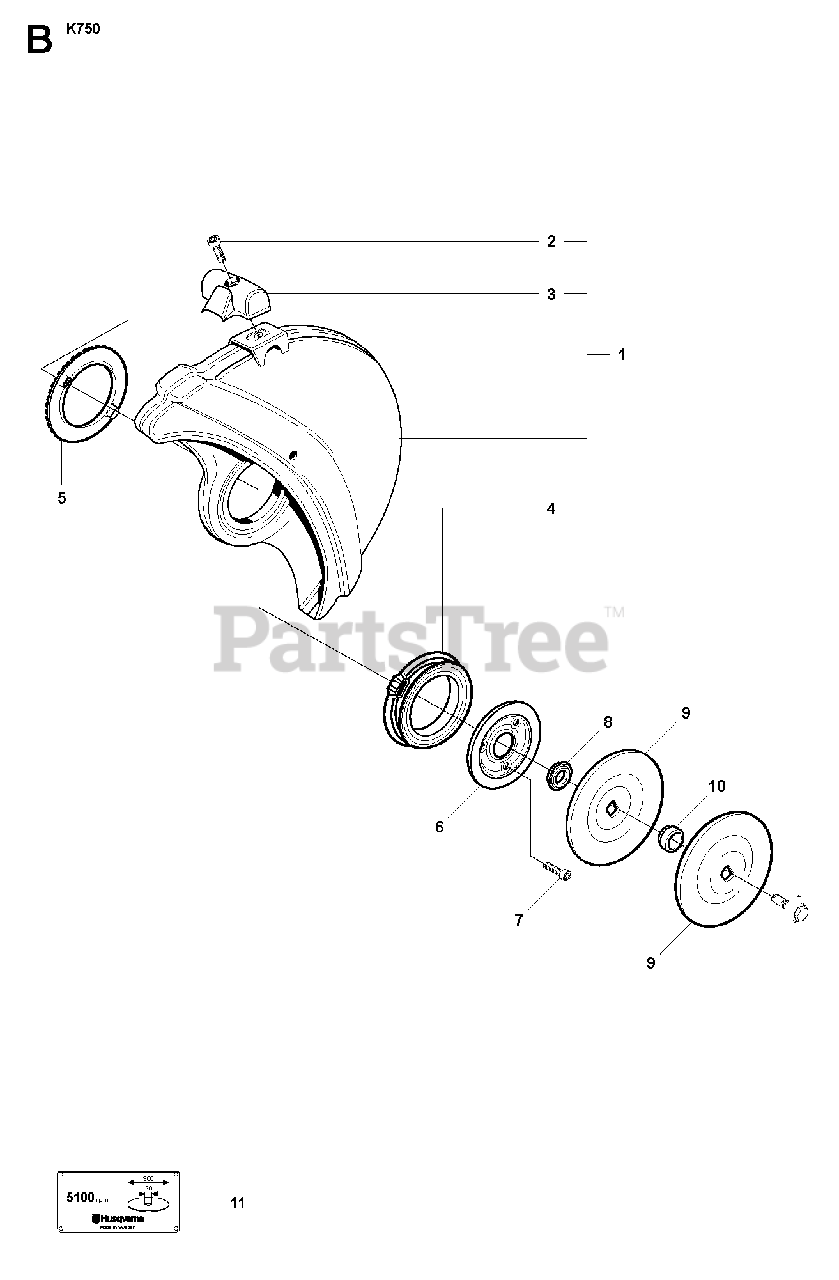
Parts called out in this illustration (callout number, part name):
1	WHEEL GUARD"12"", Incl. 2 - 4"
1	WHEEL GUARD"14"", Incl. 2 - 4"
2	SCREW IHSCM
8	SUPPORT FLANGE
9	FLANGE WASHERDiam 105 mm
9	FLANGE WASHERDiam 119 mm
10	KITDiam 20 mm
10	KITDiam 22,2 mm
10	KITDiam 25,4 mm
10	BUSHINGDiam 30,5 mm
11	LABEL"12"", Diam 1"""
11	LABEL"12"", Diam 20 mm"
11	LABEL"14"", Diam 1"""
11	LABEL"14"", Diam 20 mm"
